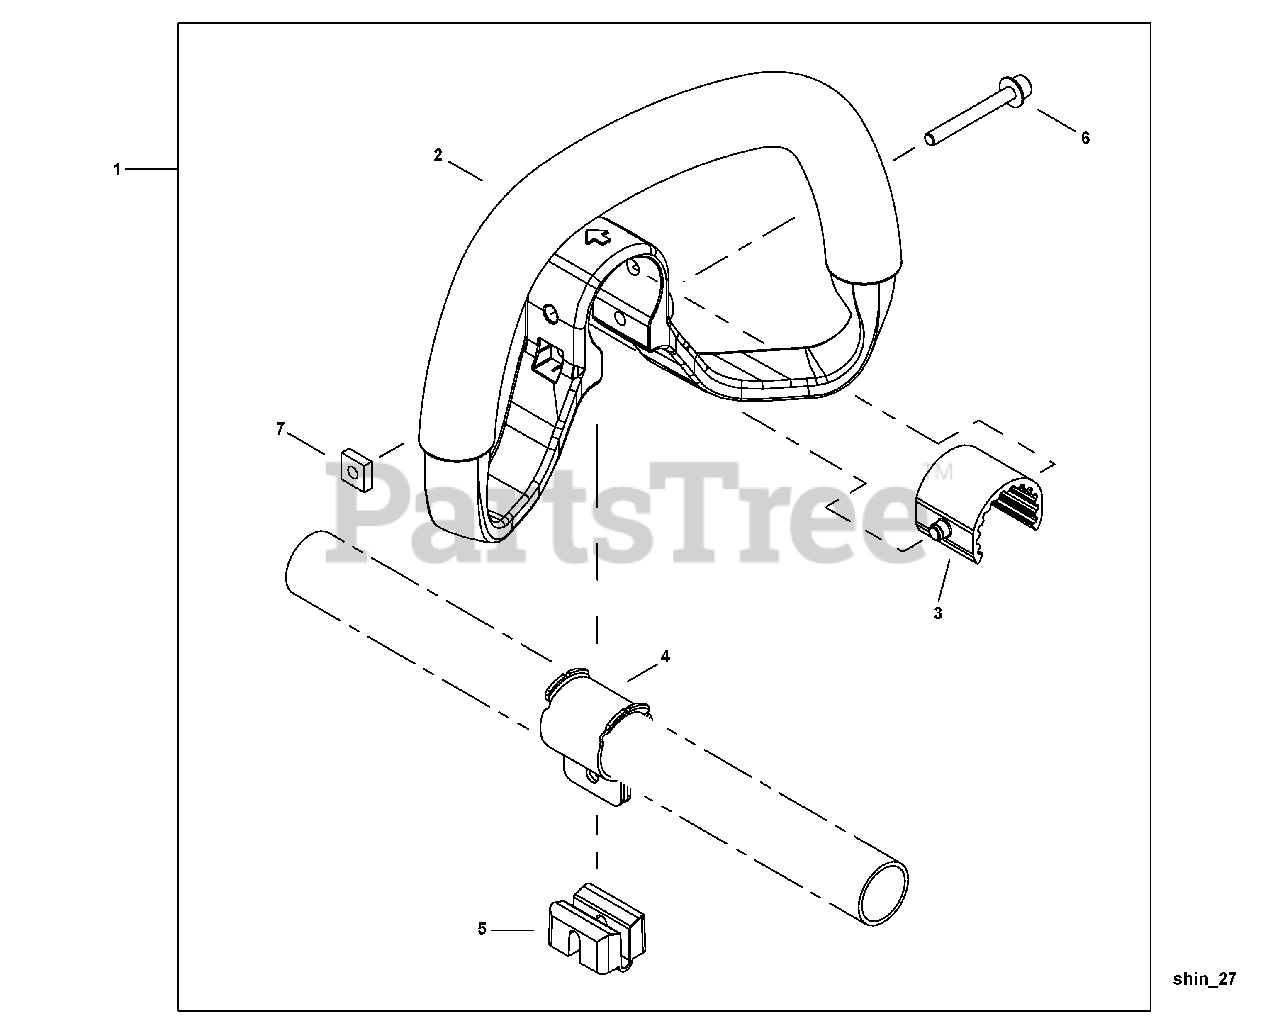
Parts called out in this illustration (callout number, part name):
1	HANDLE ASSY
2	HANDLE
3	CUSHION
4	BRACKET, MOUNTING
5	BLOCK, SPACER
6	BOLT M5×45
7	NUT M5
